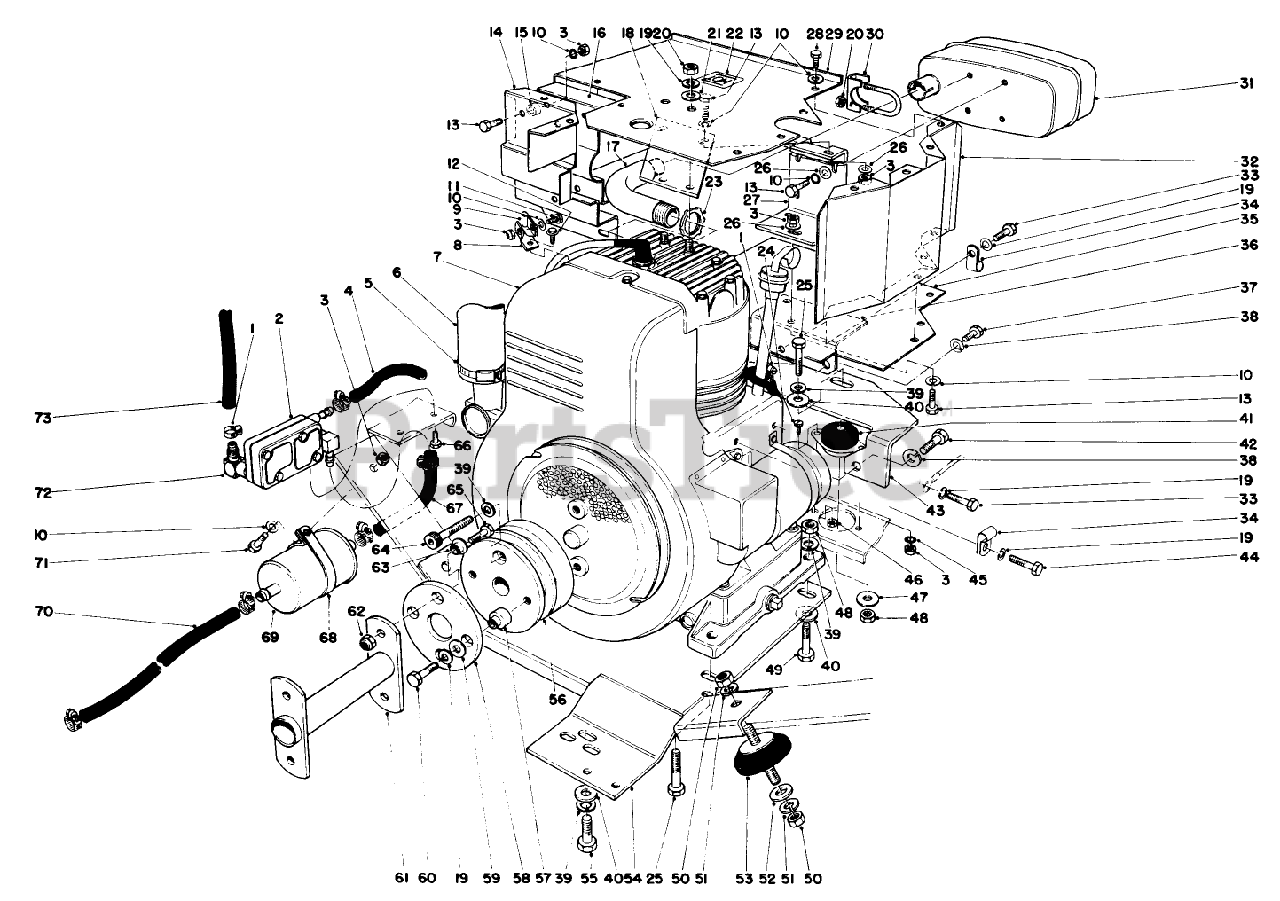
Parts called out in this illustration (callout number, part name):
1	CLAMP-HOSE
2	FUEL PUMP
3	NUT-HEX
4	PULSE LINE
5	CLAMP-HOSE
6	AIR CLEANER HOSE
7	Engine
8	BODEN CLIP BRKT
9	CLAMP-BODEN
10	WASHER-LOCK
11	SCREW
12	SCREW
13	SCREW-HH
14	REAR SHIELD WA B
15	SPACER HEAT SHIELD
16	Shield Exhaust
17	EXHAUST PIPE
18	MUFFLER BRACKET B
19	WASHER-LOCK
20	NUT-HEX
21	WASHER-PLAIN
22	Decal-Hot
23	Locknut
24	10-24 X 5/8 PAN HD MS
25	SCREW-HH
26	WASHER-FLAT
27	MUFFLER BRKT B
28	SCREW THD 1/4 20 5/8
29	Top Heat Shield
30	MUFFLER CLAMP
32	LH SIDE HT SHIELD B
33	SCREW-HH
35	Bottom Heat Shield
36	Bracket Heat Shield
37	SCREW-HH
38	WASHER-LOCK
39	WASHER-LOCK
40	WASHER-FLAT
41	RUBBER MOUNT
42	SCREW-HH
43	REAR ENGINE MT B
44	SCREW-HH
45	WASHER-LOCK
46	NUT-LOCK, NI
47	WASHER
48	NUT-HEX
49	SCREW-HH
50	NUT-HEX
51	WASHER-LOCK
52	WASHER-FLAT
53	RUBBER MOUNT
54	ENGINE BASE WA
55	SCREW-HH
56	ENGINE PULLEY BO
57	SPACER-RUBBER COUPLNG
58	COUPLING-RUBBER
59	WASHER-FLAT
60	SCREW-HH
61	DRIVE COUPLING WA B
62	NUT-HEX
63	SPACER-COUPLING
64	SCREW-HSH
65	SCREW-HH
66	Screw-Outlet
67	HOSE-FUEL
68	HOSE CLAMP
69	FiIter Gas
70	HOSE-FUEL
71	SCREW-HH
72	FITTING
73	FUEL LINE
